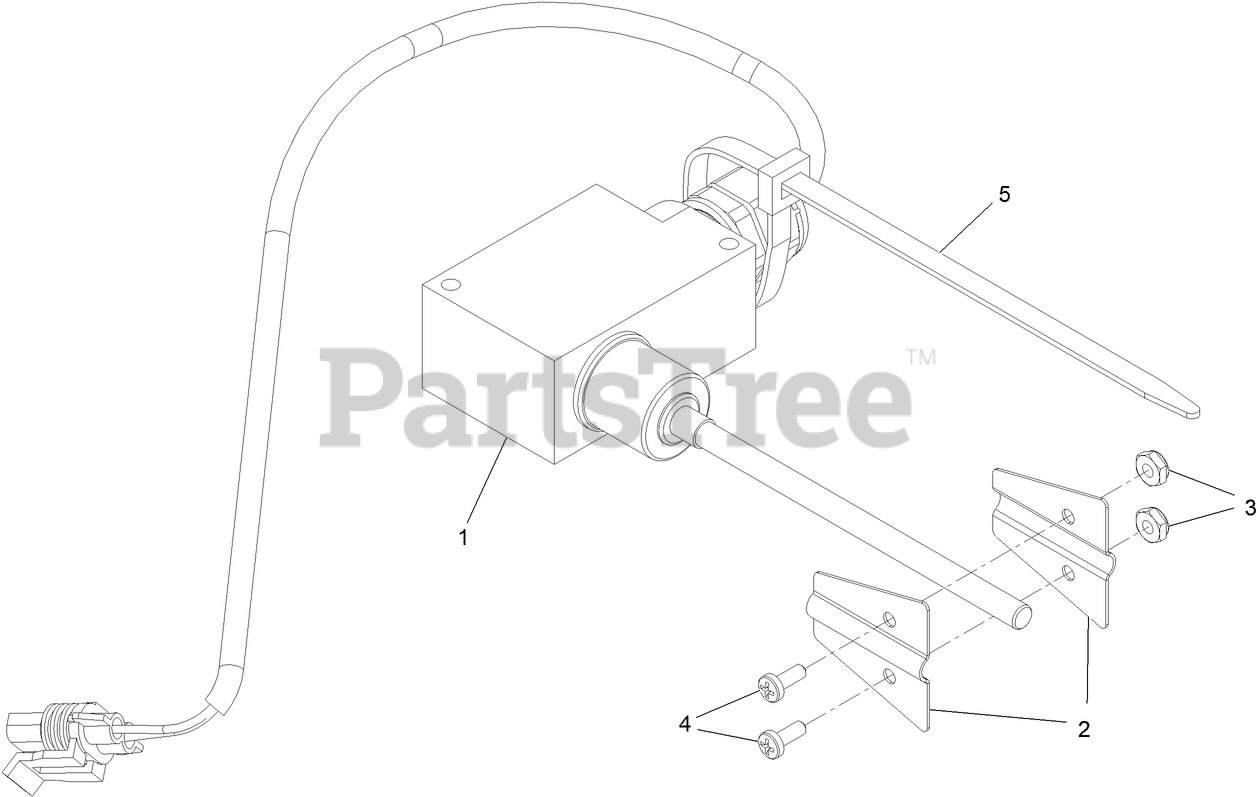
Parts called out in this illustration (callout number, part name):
1	FILL SENSOR WIRE KIT
2	FLAG-SENSOR, FILL
3	NUT-HEX
4	SCREW-PAN
5	TIE-PLASTIC
